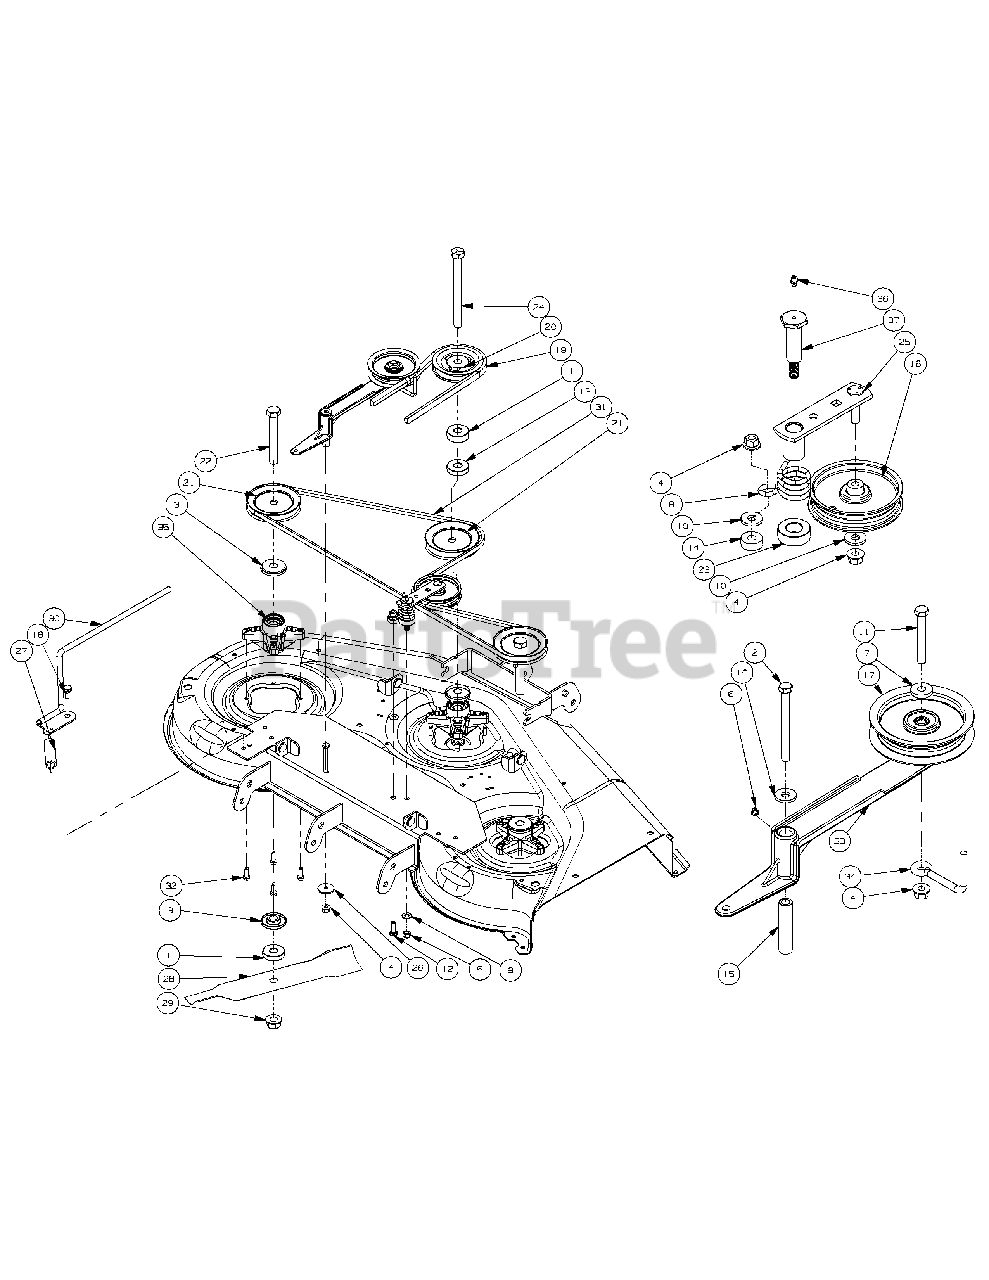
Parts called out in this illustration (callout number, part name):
1	Blade Spacer
2	Hex Cap Screw, 3/8-16, 4.00
3	Spindle Spacer
4	Hex Nut, 3/8-16, Flange Lock
5	Nut 7/16-14, Nylock
6	Grease Fitting, 1/4-28 x 3/16
7	Idler Washer
8	Idler Spring
9	Flat Washer, .469 ID x .875 OD x .105
10	Flat Washer, .406 ID x 1.0 OD x .105
11	Hex Cap Screw 3/8-16 x 2.25
12	Carraige Screw, 3/8-16 x 1.25
13	Spacer, .76 ID x 2.00 OD x .477
14	Spacer .406 ID x 1.0 OD
15	Spacer, .39 ID x .625 OD x 2.75
16	Flat Pulley
17	Idler Pulley, 4.06 OD
18	Shoulder Screw, .50 x .27 Lg., 3/8-16
19	V-Belt, Mower Drive
20	V-Pulley, 4.75 OD
21	V-Pulley, 5.0 OD
22	Hex Cap Screw 3/4-16 x 5.50
23	Spacer .760 ID x 1.5 OD
24	Hex Cap Screw, 3/4-16, 7.50
25	Idler Arm Assembly
26	Washer, 5/16-18
27	Extension Spring, .98 OD x 5.00
29	Nut, 3/4-16, Hex Flange
30	Spring Tension Rod Assembly
31	V-Belt, 1/2 x 90.9 LG
32	Self Tapping Screw 5/16-18 x 1.0
33	Idler Arm Assembly, Top
34	Belt Guide
35	Spindle Assembly
36	Grease Fitting
37	Shoulder Screw .68 x 2.11
